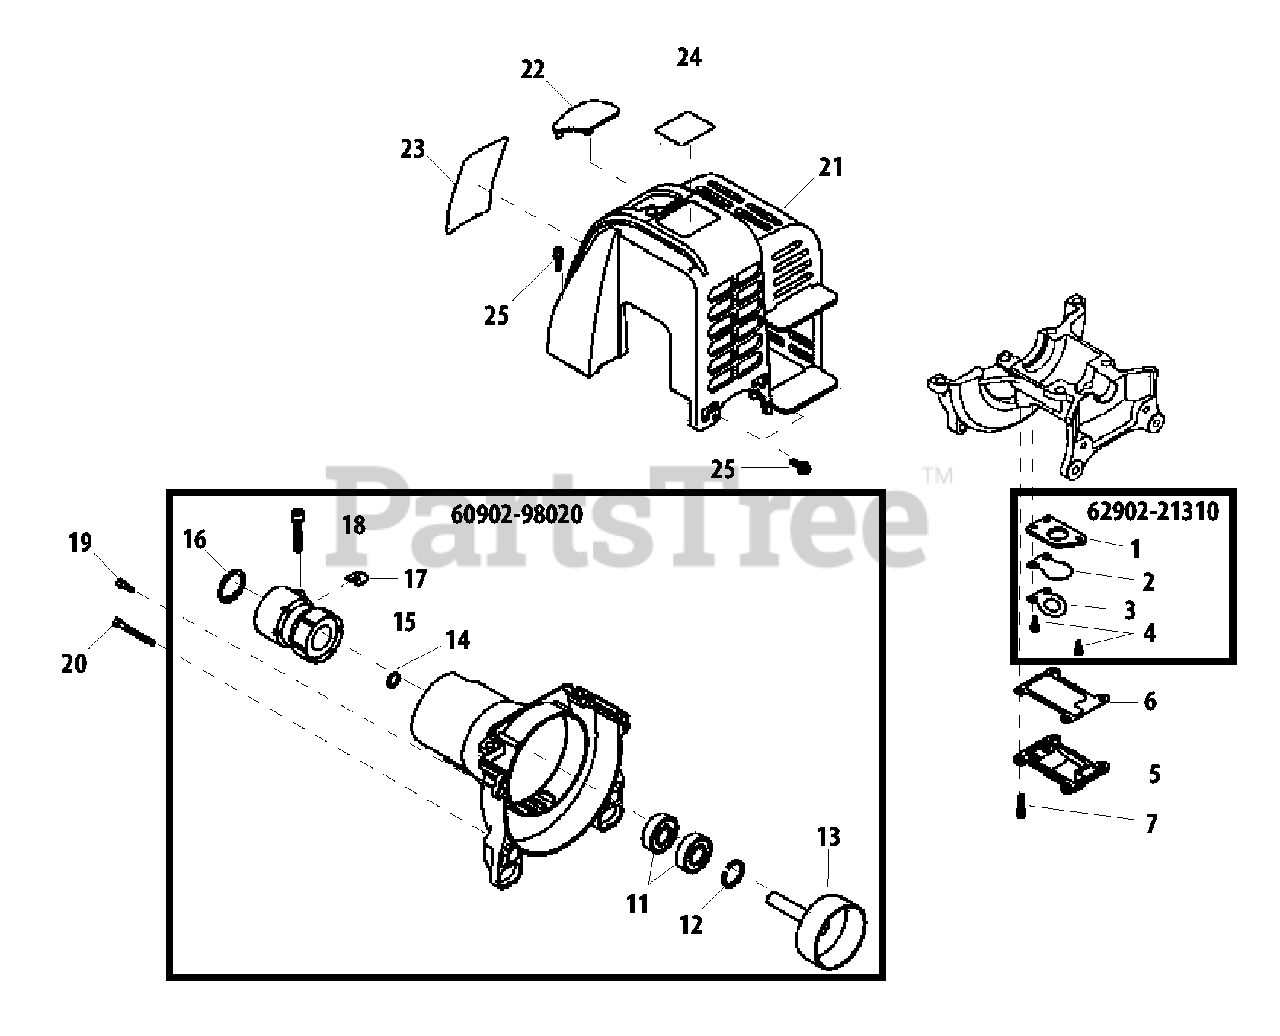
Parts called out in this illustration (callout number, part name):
1	PLATE, REED BACKING
2	VALVE, REED
3	STOP, REED VALVE
4	SCREW M3×10
5	COVER, REED VALVE
6	GASKET, REED VALVE
7	BOLT M4×12
11	BEARING, BALL 6000ZZ
12	RING, SNAP Ø26
13	DRUM, CLUTCH
14	RING, SNAP WR10
15	JOINT
16	RING, SNAP Ø40
17	D-WASHER
18	BOLT M5×22
19	BOLT 5×16
20	SCREW - 5×35
21	COVER, ENGINE
22	GROMMET
23	LABEL, C4 SHINDAIWA
24	LABEL - TRADE
25	BOLT M4×16
60902-98020	FAN CASE ASSY
62902-21310	REED VALVE ASSY
